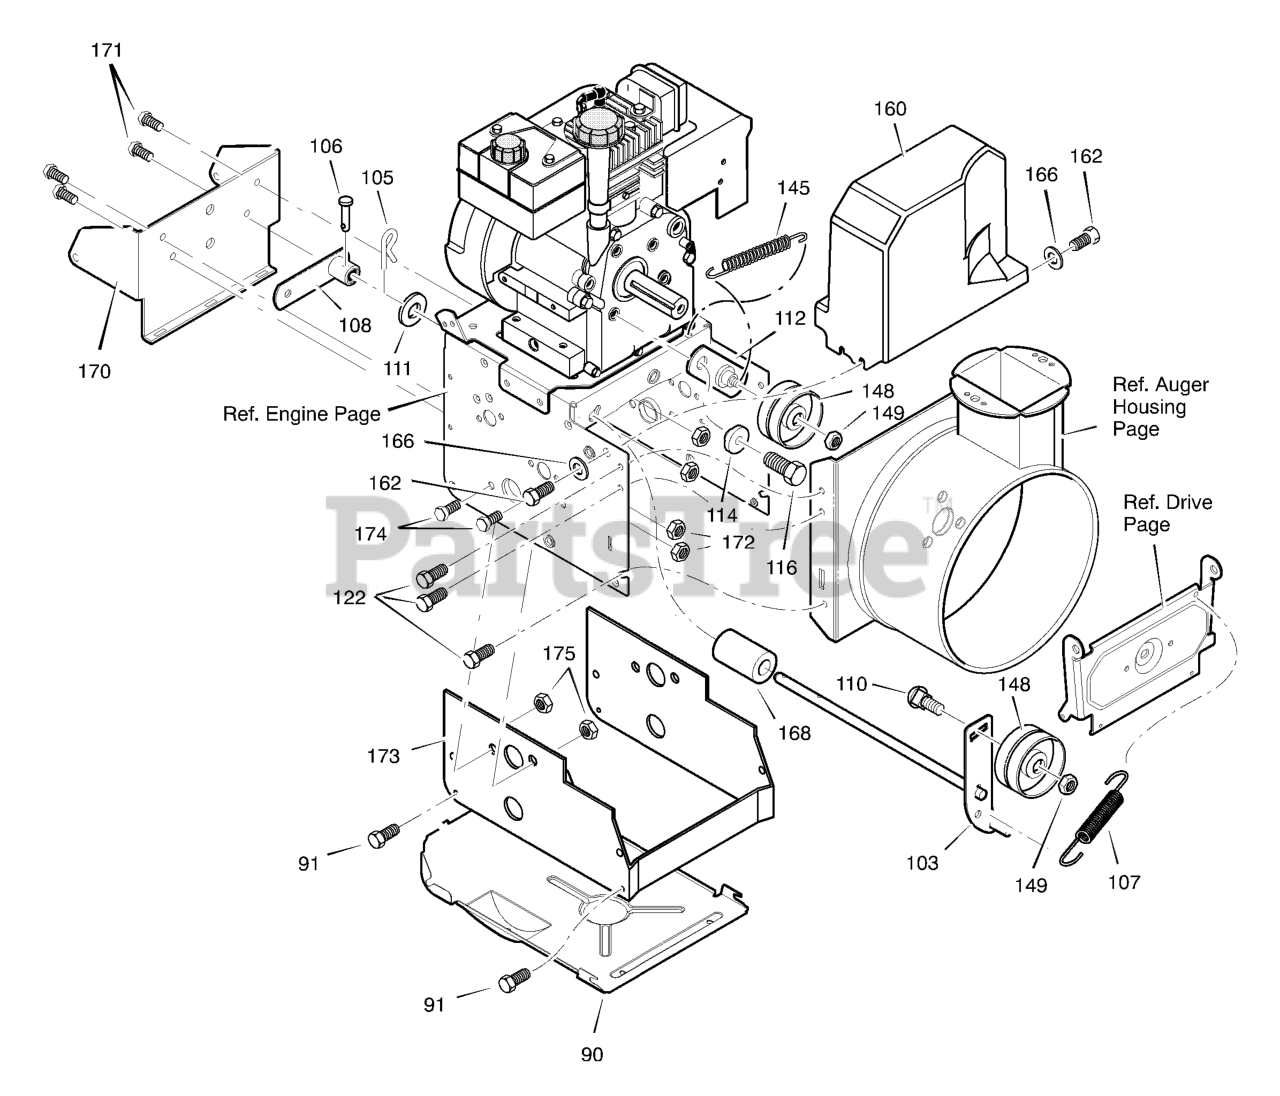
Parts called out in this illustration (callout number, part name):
90	COVER, BOTTOM
91	SCREW, 1/4-20X .63
103	IDLER ASSEMBLY, AUGER
105	PIN, HAIR .38DIAX1.64LG
106	PIN, KLIK 3/16 DIA
107	SPRING, TENSION
108	ASSY., SPRING ATTACH
110	BOLT, 3/8-16X1.25 CARR.
111	WASHER, FLAT
112	BRACKET ASSEMBLY, IDLER
114	BUSHING, IDLER BRACKET
116	SCREW 5/16-24 X .75
122	SCREW, TAP 5/16-18 X .50
145	SPRING, IDLER TRACTION DRIVE
148	PULLEY, IDLER
149	NUT, JAM 3/8-16
160	COVER, BELT
162	SCREW, TAP 1/4-20 X .63
166	WASHER, FLAT
168	SPACER, AUGER BRACKET
170	BRACKET, TRACK SUPPORT
171	SCREW, 5/16-18 x 0.75
173	EXTENSION, FRAME
174	SCREW, 3/8-16 X 0.75
175	NUT, 3/8-16
